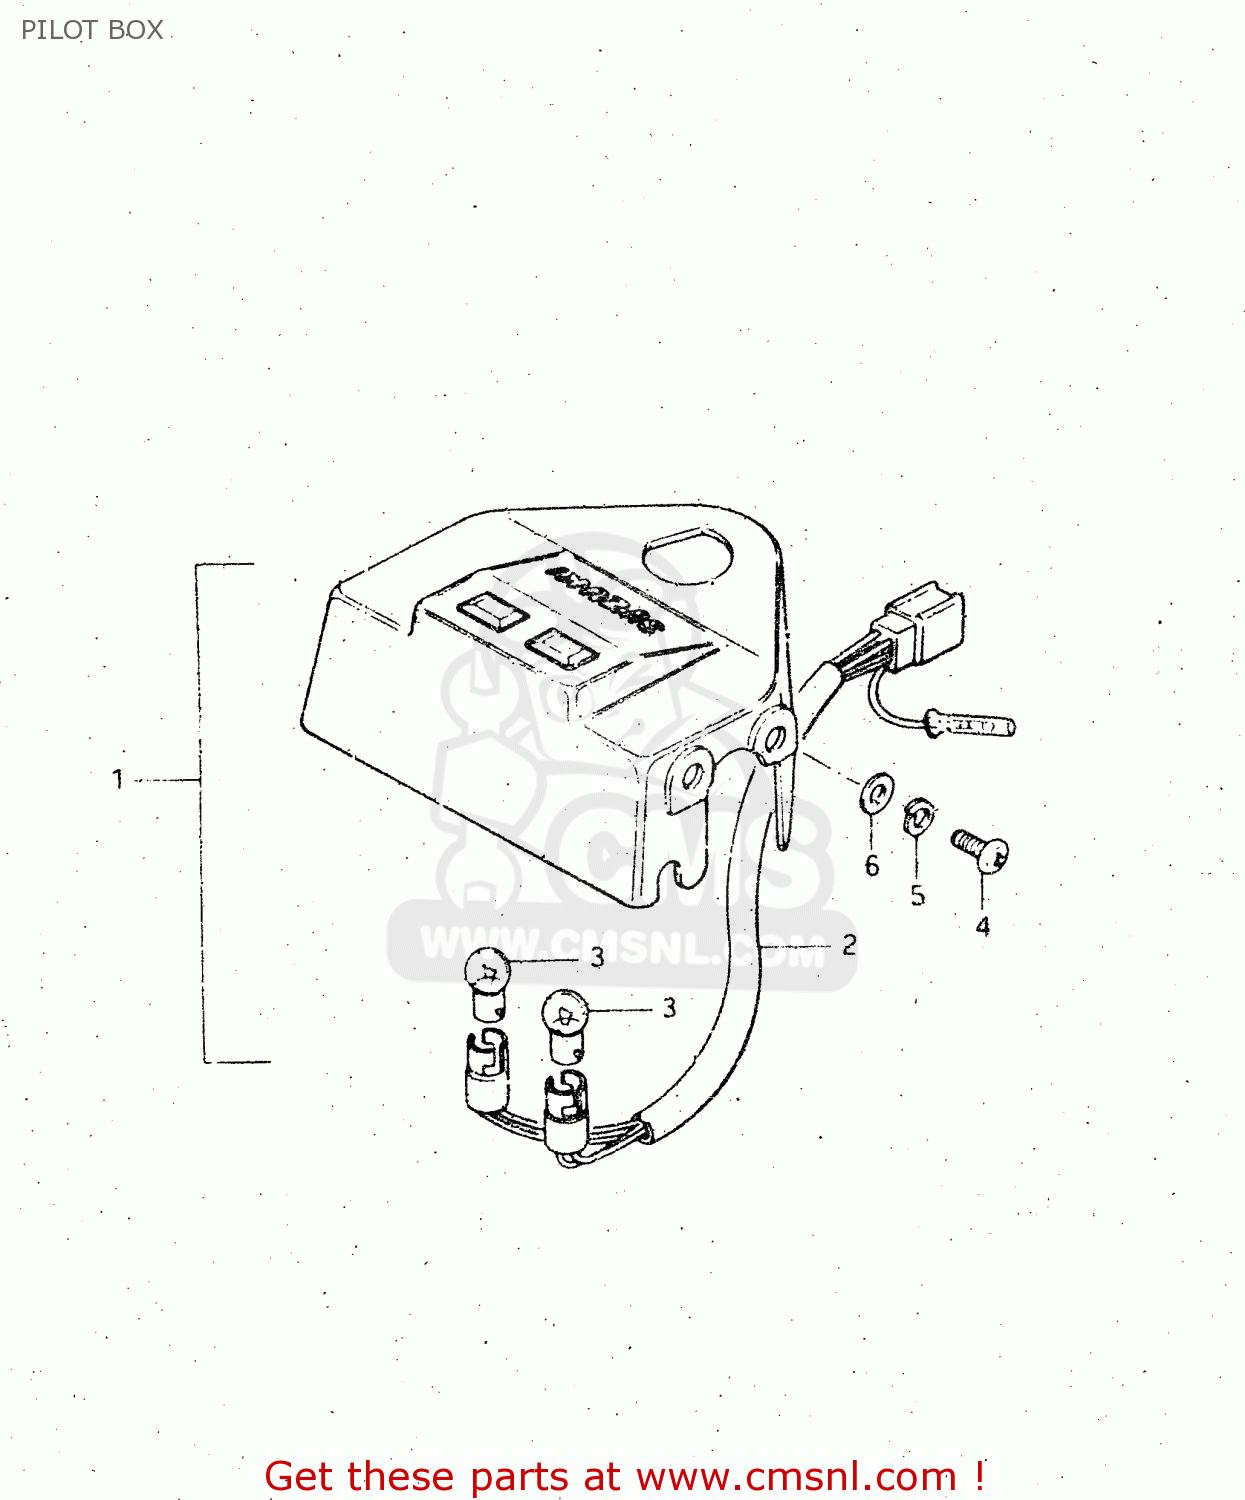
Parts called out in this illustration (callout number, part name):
1	PILOT BOX ASSY
2	SOCKET
3	BULB(6V/3W)
4	SCREW
5	WASHER,LOCK
6	WASHER,5MM
